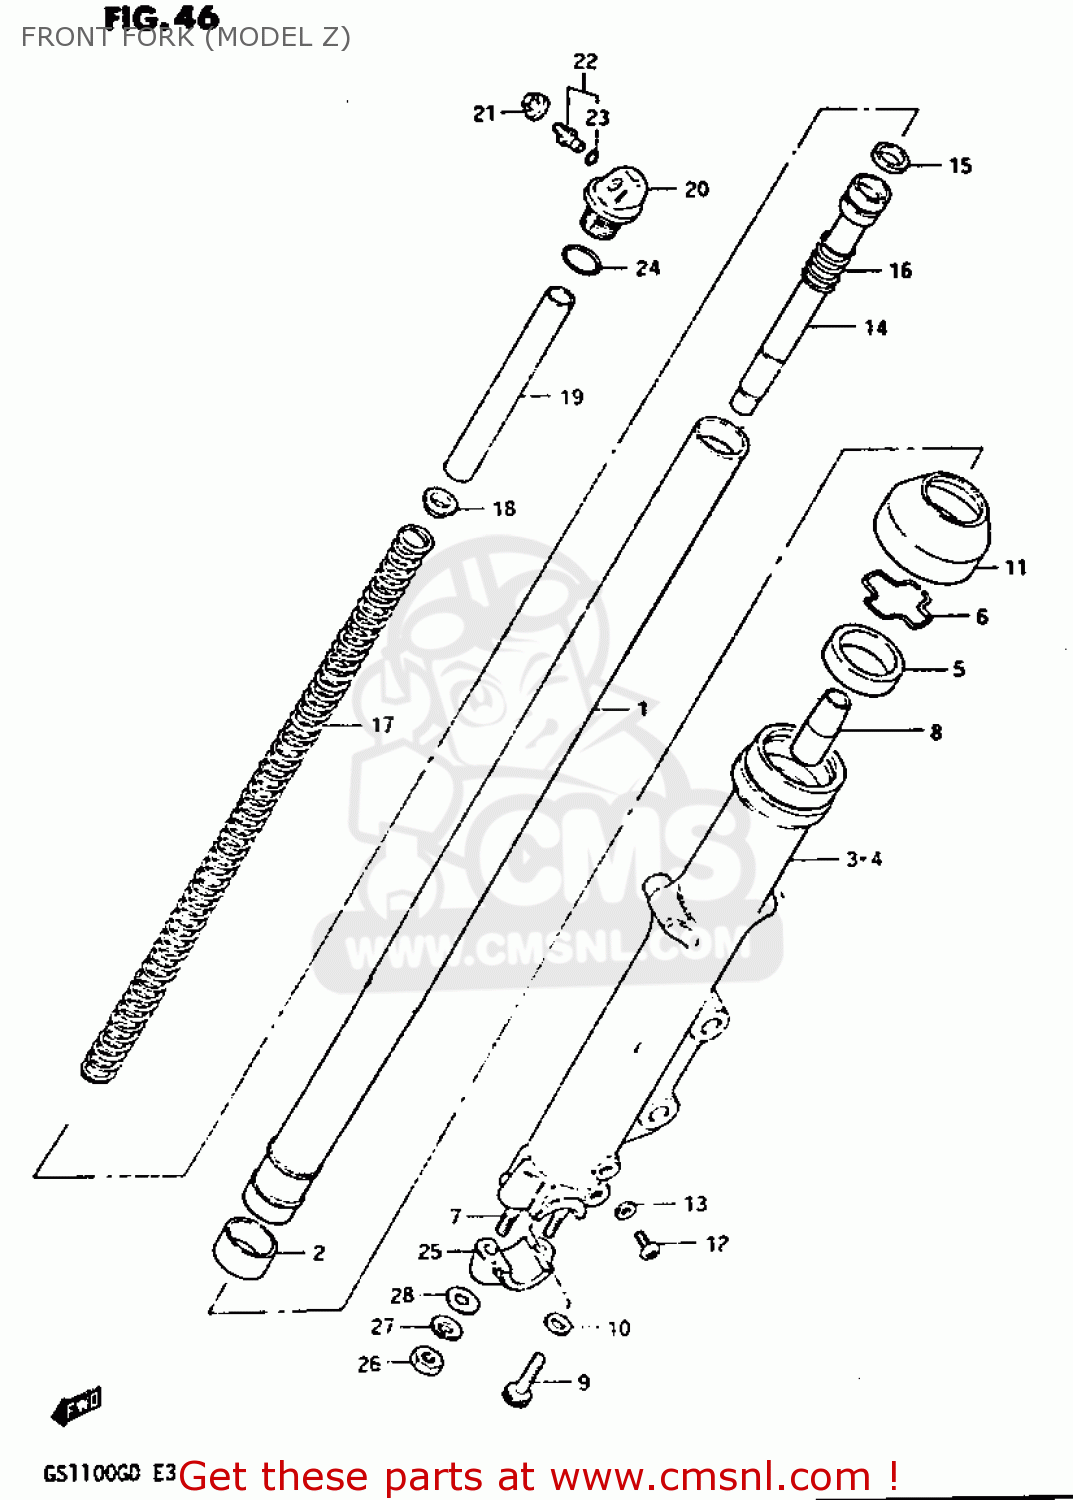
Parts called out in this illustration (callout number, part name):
1	TUBE,FORK,INNER
2	PISTON
3	TUBE,FORK,OUTER,RIGHT
4	TUBE,FORK,LEFT,OUTER
5	OIL SEAL,FRONT FORK
6	RING,STOPPER
7	BOLT,STUD
8	PIECE,OIL LOCK
9	BOLT,FORK CYLINDER(10X25)
10	GASKET (NAS)
11	SEAL,DUST
12	SCREW
13	GASKET,DRAIN,PLUG (NAS)
14	CYLINDER,FRONT FORK
15	RING,PISTON
16	SPRING,REBOUND
17	SPRING,FRONT FORK
18	GUIDE,FRONT FORK SPRING C
19	SPACER,SPRING
20	CAP
21	CAP,VALVE
22	VALVE
23	O RING
24	O RING
25	HOLDER,AXLE
26	NUT (8MM)
27	LOCK WASHER
28	WASHER
